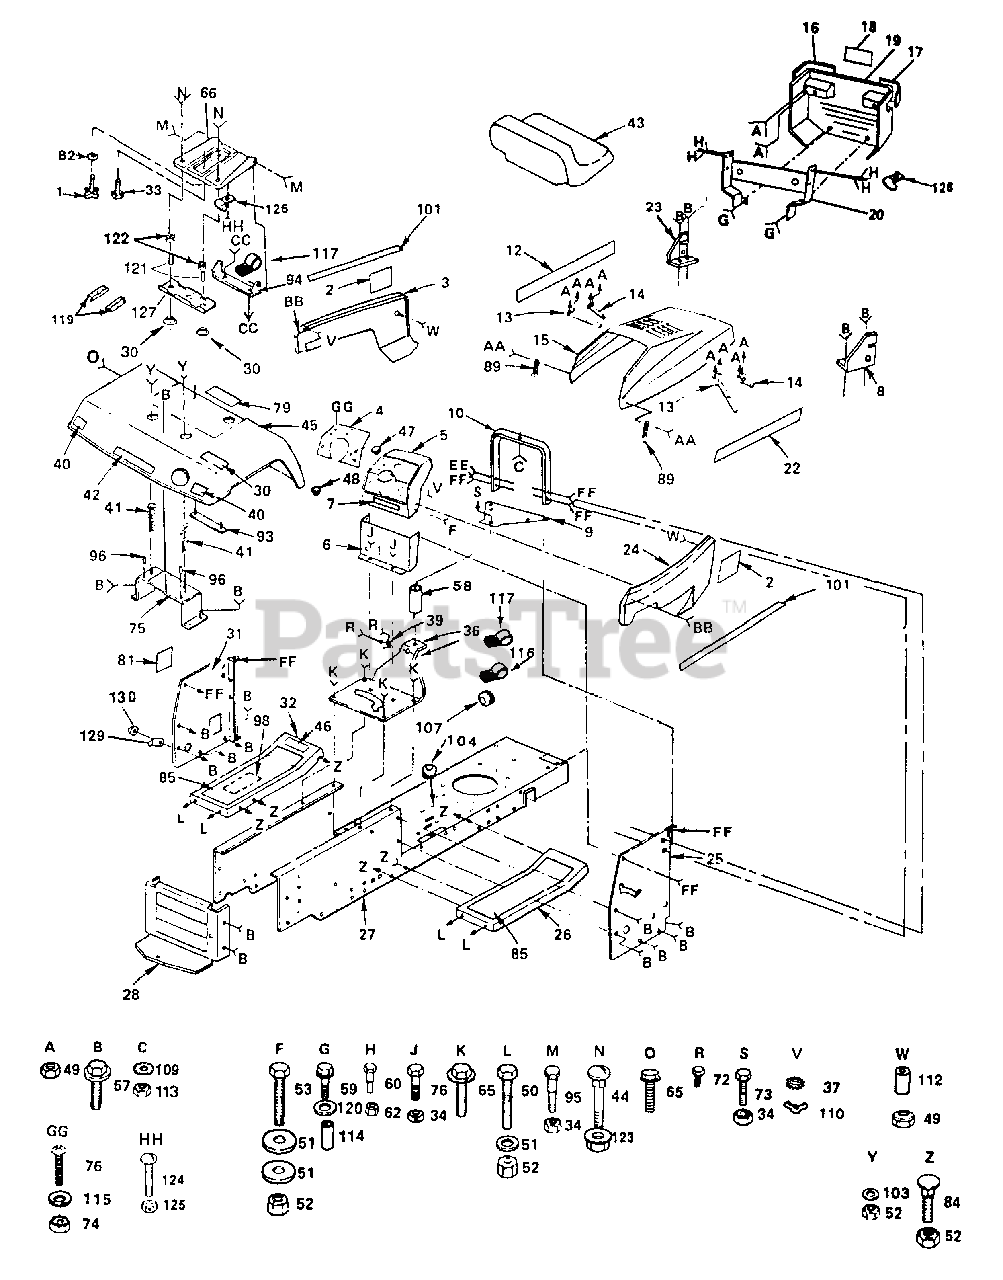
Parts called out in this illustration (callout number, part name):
1	Adjustment Knob
2	Decal, Side Panel
3	Panel, Side, L.H.
4	Dash Plate
5	Dashboard
6	Dash Assembly, Lower
7	Decal, Instruction
8	Bracket Assembly, R.H.
9	Plate, Support, Battery
10	Support Assembly, Dash
12	Decal, Hood, L.H.
13	Strap Assembly, Hinge, Rear
14	Strap Assembly, Hinge, Front
15	Hood
16	Lens, L.H.
17	Lens, R.H.
18	Decal, Grill
19	Grill Assembly
20	Support Assembly, Grill
22	Decal, Hood, R.H.
23	Bracket Assembly, L.H.
24	Panel, Side, R.H.
25	Panel, Dash, R.H.
26	Footrest, R.H.
28	Drawbar
30	Bushing, Snap
31	Panel, Dash, L.H.
32	Footrest, L.H
33	Bolt, Shoulder
34	Locknut, Gripco, 5/16-18
37	Lockwasher, 1/4 Int./Ext.
39	Bushing, Steering
40	Reflector, Taillight
41	Spring, Compression
42	Decal, Fender
43	Seat
44	Bolt, Carriage 1/4 - 20 x 11/4
46	Decal, Clutch/Brake
47	Plug, Button
48	Plug, Dash
49	Nut, Hex Keps 1/4 - 20 UNC (A)
50	Bolt, Hex 3/8 - 16 x 3/4
51	Washer, 13/32 x 13/16 x 12 Ga.
52	Nut, Crownlock 3/8 - 16
53	Bolt, Hex 3/8 - 16 x 1
57	Screw, Hex Washer Hd. Thd.
59	Bolt, 1/4 - 20 x 2 1/2
60	Bolt, Shoulder 1/4-20
62	Nut, Crownlock 1/4 - 20
65	Screw, Hex Wsh. Thdrol. 3/8 - 16 x 1/2
69	Screw, Hex Wsh. Thdrol. 3/8 x 16 x 1/2
72	Screw, Hex Head Self Tapping, No.10 - 16 x 1/2 Type B
73	Bolt, Hex 5/16-18 x 2 Gr 2
74	Nut, Keps 5/16-18
75	Bracket Assembly, Fender
76	Screw, Mach. 5/16-18 x 3/4
79	Decal, Caution
81	Cover, Access
82	Washer, 17/32 x 1-3/16 x 12 Ga.
84	Bolt, Carriage 3/8 - 16 x 3/4
85	Pad, Footrest
89	Latch, Hood
93	Strap Assembly, Fender
94	Bracket, Pivot, Seat
95	Bolt, Shoulder 5/16-18
98	Decal, V-Belt Drive, Schematic
101	Decal, Side Panel
103	Washer, 13/32 x 1 x 14 Ga.
107	Grommet, Split
109	Lockwasher, 1/4 Int. Ext.
110	Wing Nut, 1/4-20
113	Nut, Hex 1/4 - 20
115	Washer, 11/32 x 11/16 x 16 Ga.
116	Clip, Insulated
117	Clip, Insulated
119	Foam Strip
120	Washer 9/32 x 3/4 x 16 Ga.
121	Spacer Split, 0.28 x 0.88
122	Spring, Compression
123	Nut, Hex, Flanged 1/4-20 UNC
124	Screw, Slotted Pan Head, #10-32 x 1/2
125	Nut, Keps, #10-32 UNF
126	Clip, Insulated
127	Bracket, Switch Mount
128	Scale, Height Indicator
129	Pointer, Height Indicator
130	Washer, Nylon .44 x .75 x .032
132	Decal, Grill
133	Washer, 13/32 x 3/4 x 10 Ga.
